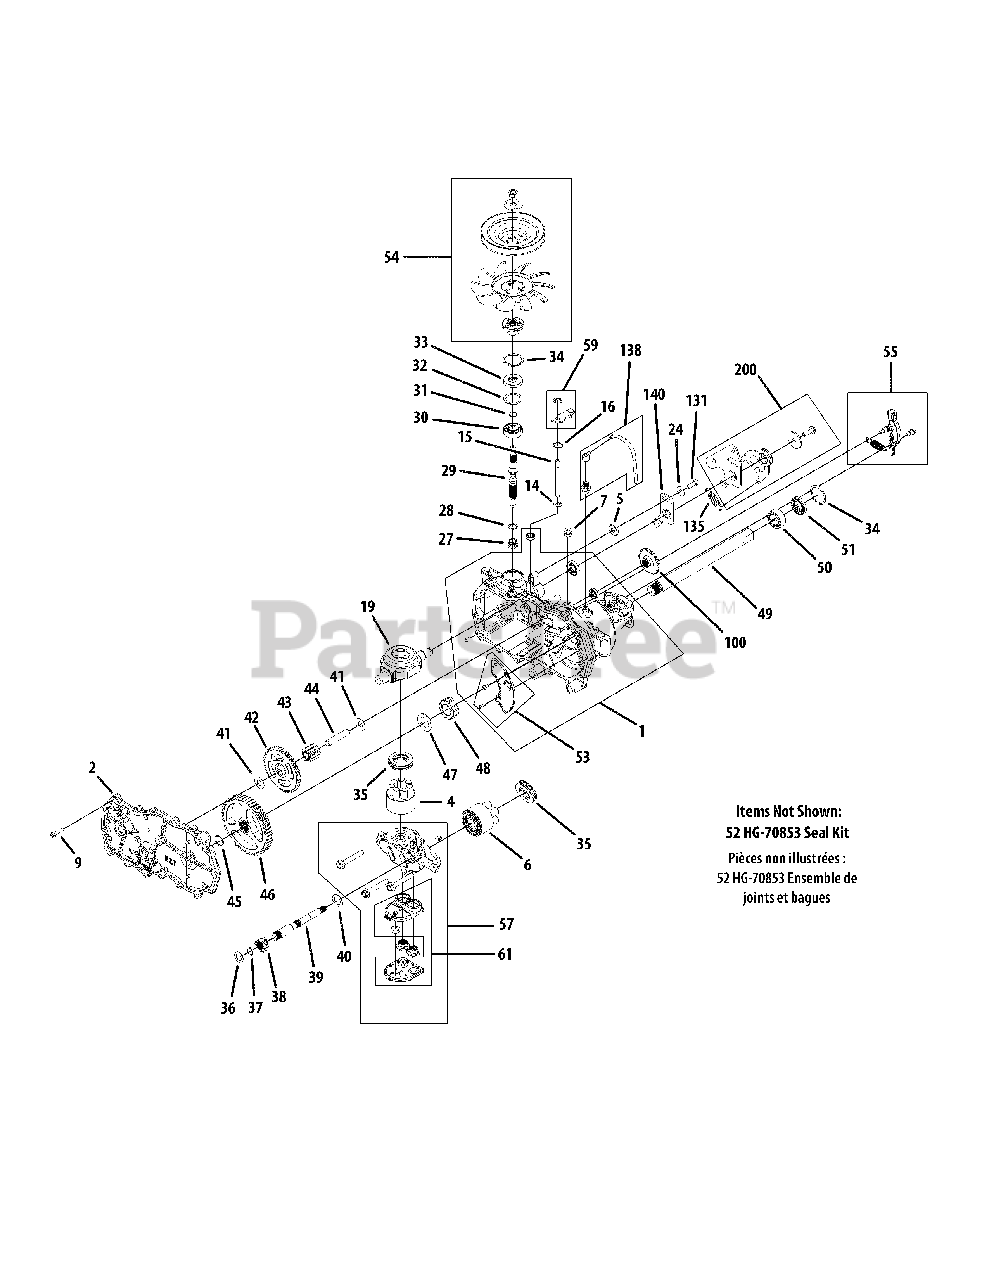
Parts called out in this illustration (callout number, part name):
1	Housing Ass’y, Main RH
2	Side Assembly LH
4	Block Kit - 7 Piston
5	Spacer, .32 x 1.005 x .179
6	Block Assembly, Cylinder
7	Straight Thread Pipe
9	Hex Washer Screw
14	Retaing Ring .375 Ext.
15	Rod, Bypass
16	Retaining Ring .75 Int.
19	Swashplate, trunnion
24	Washer .34 ID x .88 OD x .06
27	Block Washer
28	Block Thrust Washer
29	Input Shaft
30	Ball Bearing
31	Retaining Ring
32	Spacer
33	Lip Seal
34	Retaining Ring
35	Thrust Bearing
36	Flat Washer 5/8 x 1.0 x .05
37	Retaining Ring
38	Gear, Pinion, 13T
39	Shaft, Motor
40	Motor Shaft Washer
41	Washer, HT
42	Gear, 10T/48T
43	Gear, 10T Jackshaft
44	Pin, Jackshaft
45	Retaining Ring
46	Gear, Bull, 52T
47	Washer, 1.018 x 1.57 x .105
48	Sleeve Bearing
49	Shaft, Axle, 1.0 x 11.7
50	Bearing, Sleeve
51	Seal, Lip
52	Kit, Seals & Rings
53	Plate Kit, Expansion
54	Kit, Fan & Pulley
55	Kit, Brake Arm
57	Kit, Center Section RH
59	Kit, Bypass Arm RH
61	Filter Assembly
100	Disc, Brake Cog
131	Socket Cap Screw 5/16-24 x 7/8
135	Extension Spring
138	Breather Kit
140	Neutral Arm RH
200	Kit, RTN Bidirectional
